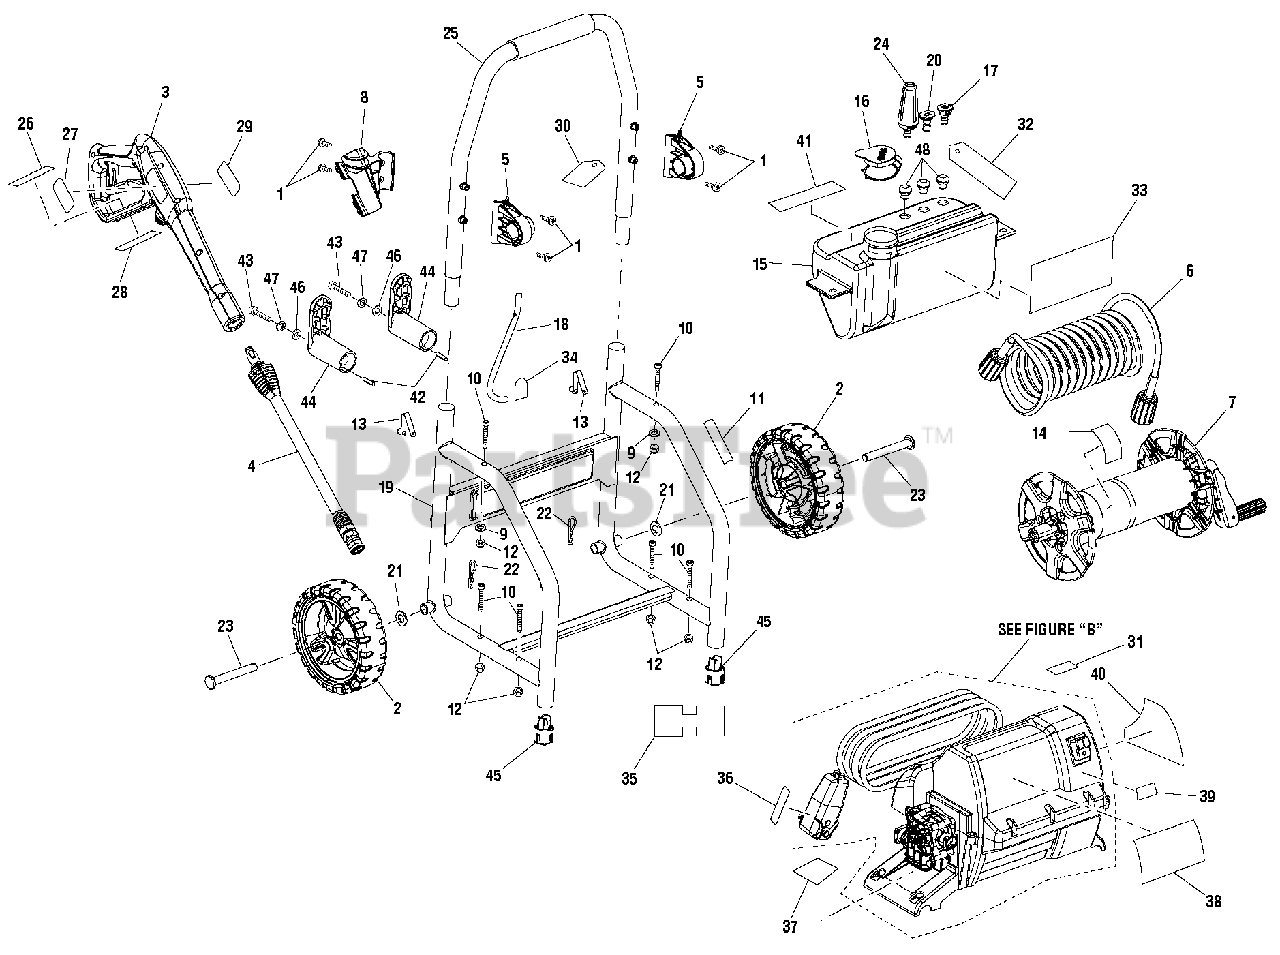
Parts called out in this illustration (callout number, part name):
1	Bolt (M6 x 20 mm, Ph. Hd.)
2	Wheel Assembly
3	Trigger Handle
4	Spray Wand
5	Bracket (Hose Reel)
6	High Pressure Hose (20 ft)
7	Hose Reel
8	Trigger Handle Holder
9	Washer (M6)
10	Bolt (M6 x 40 mm)
11	Inquiries Label
12	Lock Nut (M6)
13	Spring Clip
14	Hose Wrap Label
15	Soap Tank Assembly
16	Soap Tank Cap
17	Soap Nozzle
18	Chemical Siphon Tube
20	15deg Nozzle
21	Washer (OD12.5 x ID24 x 2t)
22	Cotter Pin
24	Turbo Nozzle
25	Handle Assembly
26	Trigger Handle Rating Label
27	Logo Label (Trigger Handle)
28	Warning Label (Trigger Handle)
29	Trigger Handle Warning Label (Eng)
30	Warning Hangtag
31	Soap Dilution Label
32	Nozzle Hangtag
33	Performance Label
34	Power Cord Unlock Label
35	Cord Wrap Warning Label
36	Cord Label
37	Data Label
38	Logo Label
39	On/Off Label
40	Icon Label
41	Quick Start Label
42	Roll Pin (M3 x 25 mm)
43	Bolt (M6 x 25 mm, Hex Soc. Hd.)
44	Cord Wrap Arm
46	Washer (M6)
47	Lock Washer (M6)
